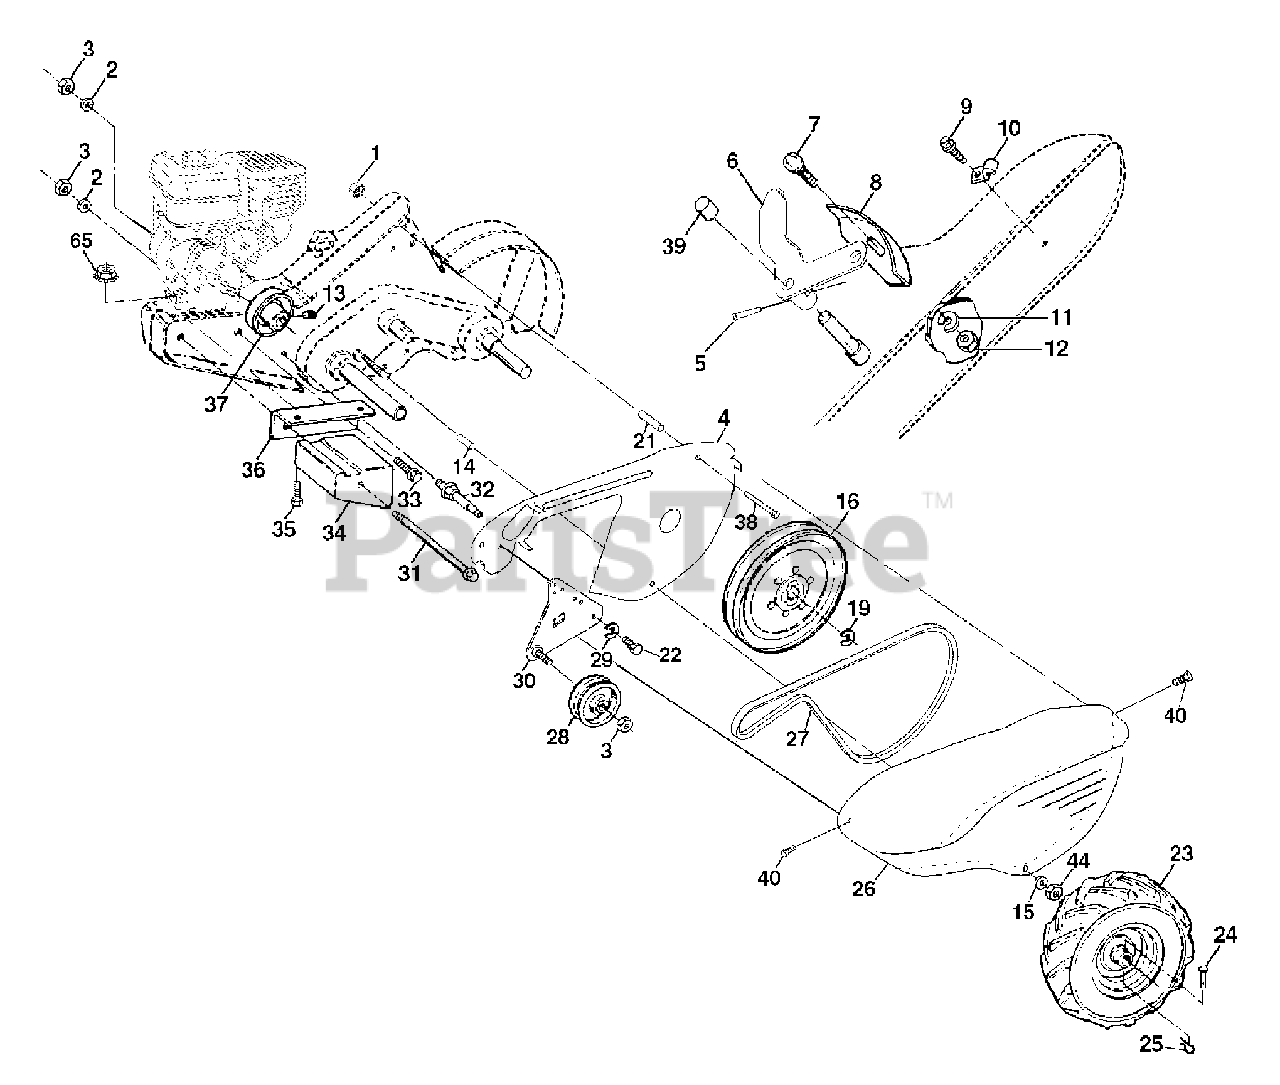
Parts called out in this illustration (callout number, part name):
1	Nut, Keps 5/16-18
2	Washer, Lock 3/8
3	Nut, Hex 3/8-16
4	Shield, Inner, Belt Guard
5	Pin Spirol Flared
6	Lever, Shift
7	Bolt, Carriage 1/4-20 x 1/2 Gr. 5
8	Plate, Shift Indicator
9	Screw, Hex, Washer Head, Slotted #10-24 x 1/2
10	Clip
11	Washer, Lock 1/4
12	Nut, Hex 1/4-20
13	Screw, Set, Hex 5/16-18 x 3/8
14	Spacer, Split 0.327 x 0.42 x 1.220
15	Washer 11/32 x 11/16 x 16 Ga.
16	Sheave, Transmission
19	Ring, Retainer
21	Spacer, Split 0.327 x 0.42 x 2.09
22	Bolt Hex 5/16-24 x 1/2
23	Tire
23	Rim
23	Tire Valve
24	Rivet, Drilled
25	Clip, Hairpin
27	Belt, V
28	Pulley, Idler
29	Ring, Klip
30	Bracket, Idler
31	Bolt, Hex 5/16-16 x 12
32	Shaft, Idler Arm
33	Bolt, Hex 3/8-16 x 1
34	Counterweight, L. H.
35	Bolt, Hex 5/16-18 x 1-1/2
36	Bracket, Reinforcement, L. H.
37	Sheave, Engine
38	Bolt, Hex 5/16-18 x 2-3/4
39	Cap, Plunger
40	Screw, Hex Wsh Slt #10-24x .50
43	Nut, Lock #10-24
44	Nut, Lock 5/16-18
65	Nut, Lock Hex Flange
